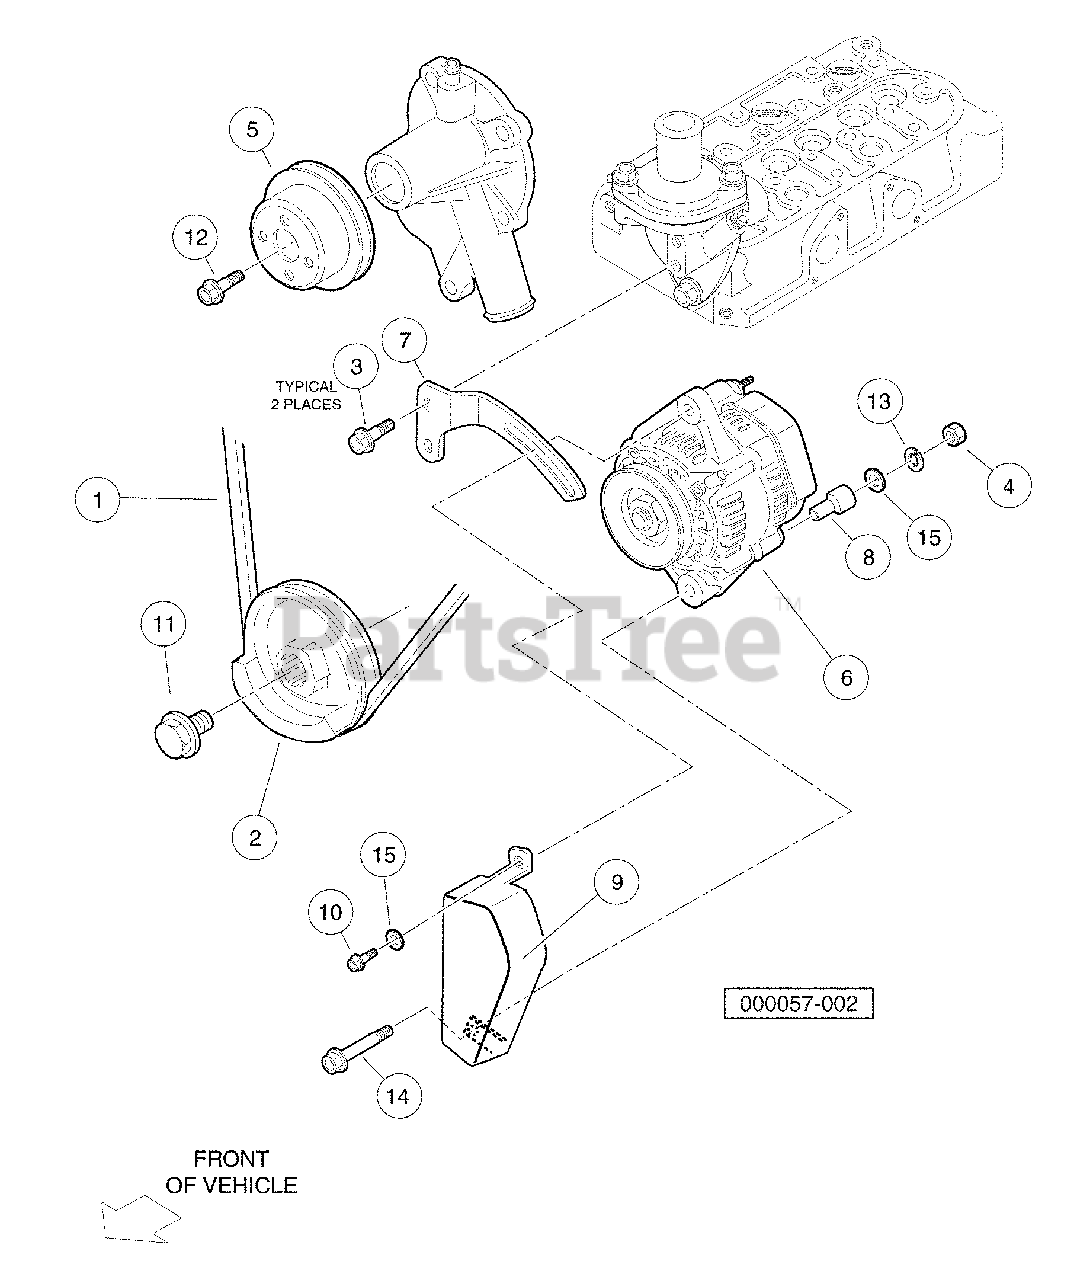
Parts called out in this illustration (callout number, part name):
2	Pulley, Fan Drive
3	Bolt, M6 X 1 X 20
4	Nut, M8, Plate
5	Pulley, Water Pump
6	Alternator, 40-Amp
7	Stay, Alternator Assy, D722
8	Collar, Alternator Assy, D722
9	Cover, Alternator Assy, D722
10	Bolt, Alt, D722, Adjuster
11	Bolt, Alt, D722, Drive Pulley
12	Bolt, D722, Drive Pulley
13	Washer, Spring, D722, Starter
14	Bolt, Alternator, Lower
15	Washer, Alternator, Upper
